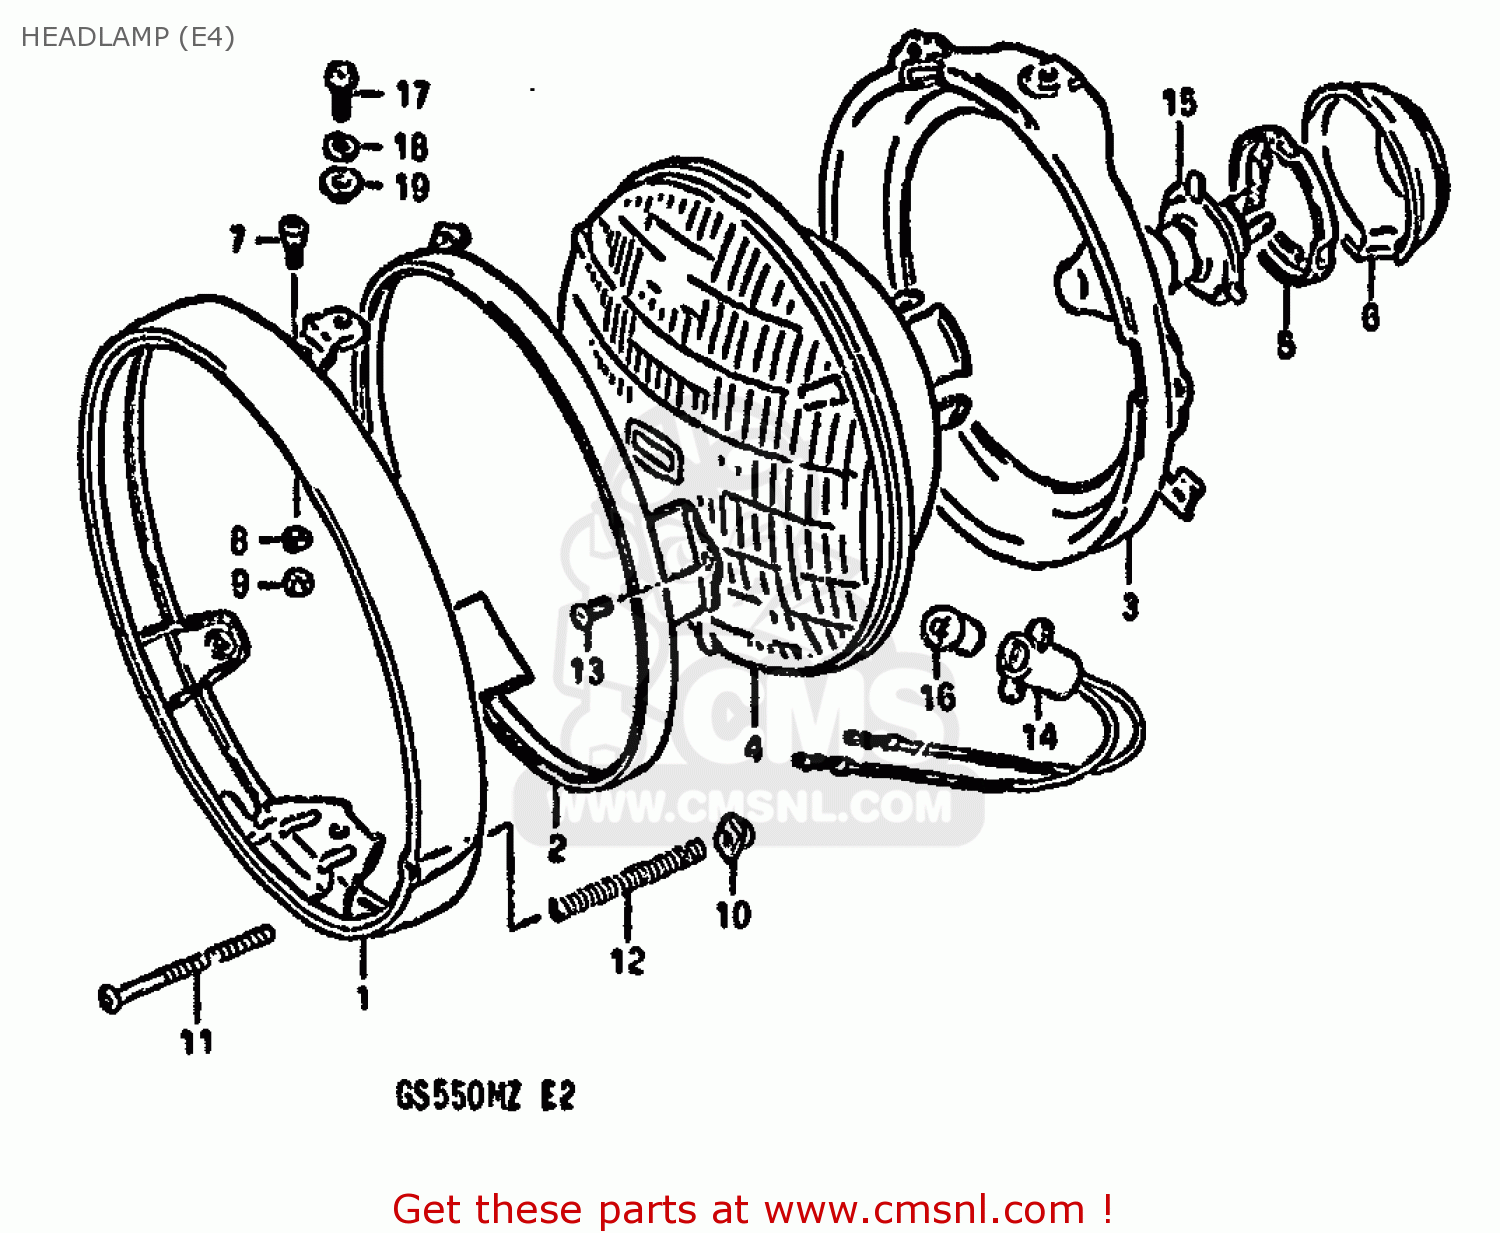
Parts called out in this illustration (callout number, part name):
1	RIM,HEADLAMP
2	RETAINING RING
3	RING
4	UNIT,HEAD LAMP
5	SETTING,BULB
6	COVER,HEADLAMP SOCKET
7	H/LAMP LENS UNIT FITING SCRE
8	LOCK WASHER
9	NUT
10	NUT
11	SCREW,HEADLAMP ADJUST
12	SPRING,ADJUSTING
13	SCREW
14	SOCKET
15	BULB (12V, 60/55W, H4)
16	BULB(12V4W)
17	SCREW
18	WASHER,LOCK
19	WASHER
